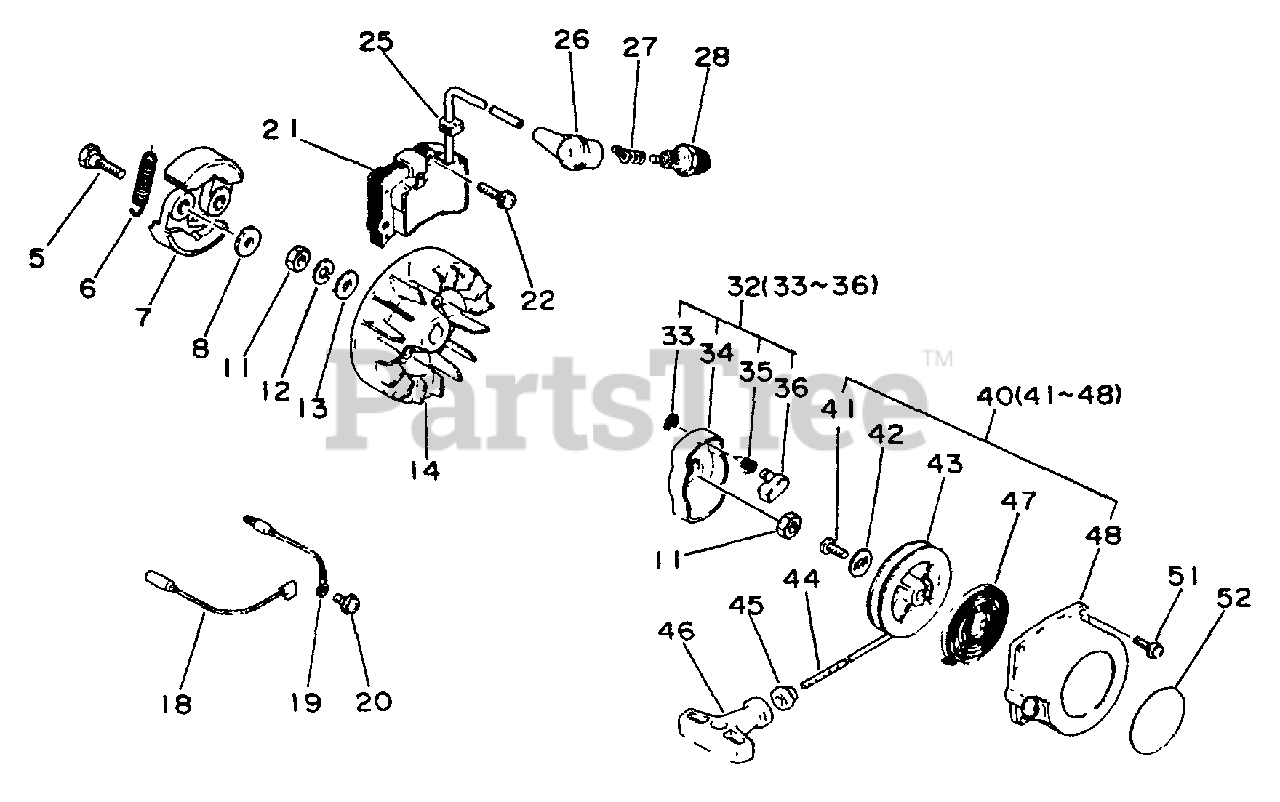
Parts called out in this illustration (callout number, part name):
5	BOLT, CLUTCH
6	SPRING, CLUTCH
7	SHOE, CLUTCH
8	WASHER - 6
12	LOCKWASHER - 8
13	WASHER - 8
14	FLYWHEEL
18	LEAD - GROUND
19	LEAD - GROUND
20	SCREW - 5X10
21	COIL, IGNITION
22	SCREW - 5X20
26	CAP, SPARK PLUG
27	TERMINAL, SPARK PLUG CAP
28	SPARK PLUG -- CJ-7Y
32	STARTER PAWL ASSY
33	RING, RETAINING - 6
34	CATCHER, PAWL
35	SPRING, RETURN
36	PAWL, STARTER
40	STARTER ASSY
42	WASHER
43	REEL, ROPE
44	ROPE, STARTER - 3.5X850
45	GUIDE, ROPE
46	GRIP, STARTER
47	SPRING, REWIND
48	CASE, STARTER
51	SCREW - 4X14
52	LABEL - ECHO
